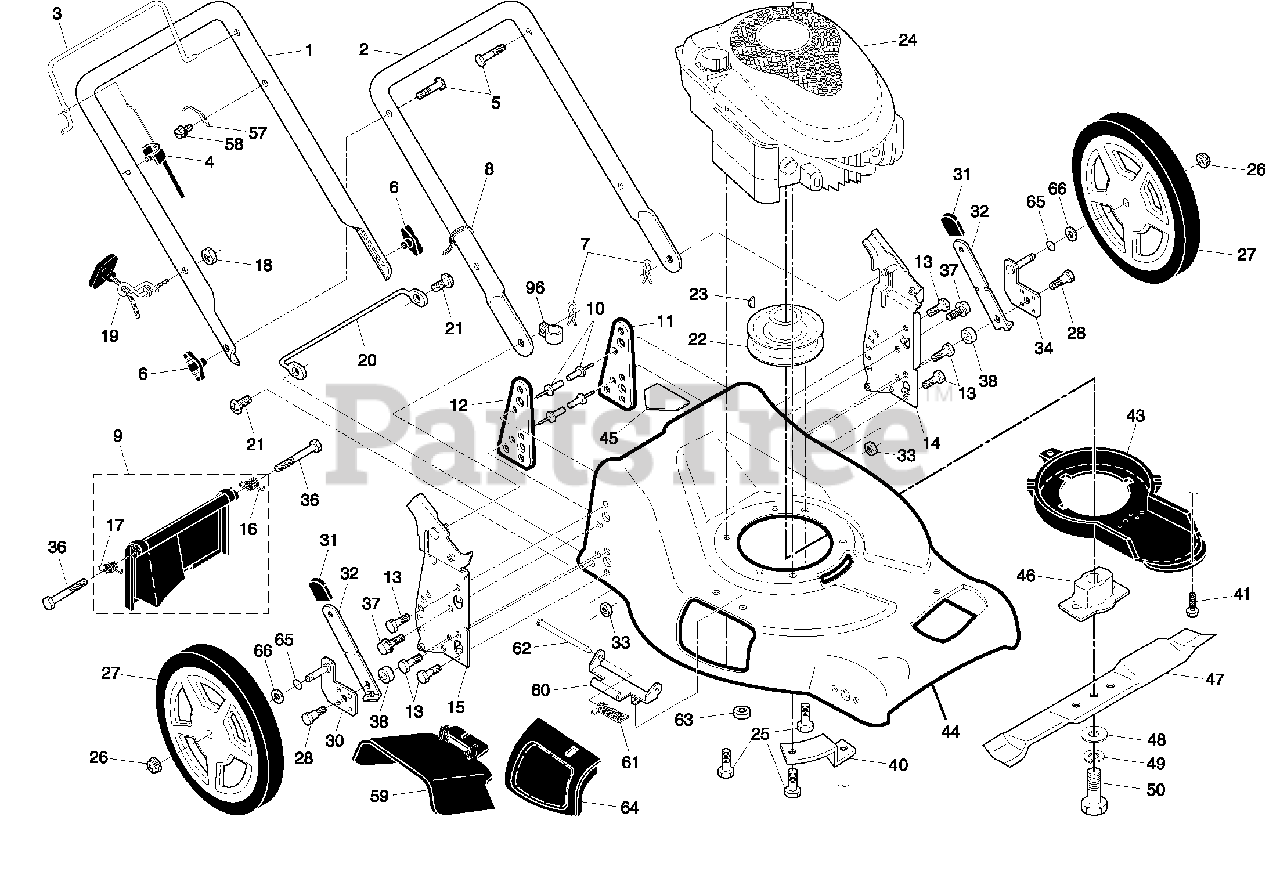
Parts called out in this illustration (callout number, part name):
1	Upper Handle
2	Lower Handle
4	Engine Zone Control Cable
6	Handle Knob
7	Hairpin Cotter
8	Wire Tie
9	Rear Door Kit
11	Support Bracket, LH
12	Support Bracket, RH
13	Screw 1/4-20 x 5/8
14	Handle Bracket Assembly, LH
15	Handle Bracket Assembly, RH
16	Spring, Rear Door, LH
17	Spring, Rear Door, RH
18	Keps Locknut 1/4-20
19	Rope Guide
20	Foot Guard, C.E.
21	Screw, Tapping 1/4-20 x 1/2
22	Engine Pulley
25	Hex Head Thread Rolling Screw 3/8-16 x 1-1/8
26	Hex Flange Nut
27	Wheel & Tire Assembly
28	Shoulder Bolt 5/16-18 x .33
30	Axle Arm Assembly, Rear, RH
31	Selector Knob
32	Selector Spring
33	Nut, Hex 5/16-18
34	Axle Arm Assembly, Rear, LH
36	Bolt, Hex Head
37	Screw 5/16-18 x 3/4
40	Mounting Bracket, Debris Shield
43	Debris Shield
44	Kit, Housing
45	Danger Decal
46	Blade Adapter
47	Blade, 21"
48	Hardened Washer
49	Helical Washer 3/8-24 x 1-3/8 Grade 8
50	Hex Head Machine Screw 3/8-24 x 1-3/8 Grade 8
57	Bracket, Upstop
58	Screw, Threaded 10-24 x 1/2
59	Discharge Deflector
60	Hinge Bracket
61	Spring, Torsion
63	Nut, Hex
96	Operator's Manual, European
96	Operator's Manual, Scandinavian
96	Repair Parts Manual, English
